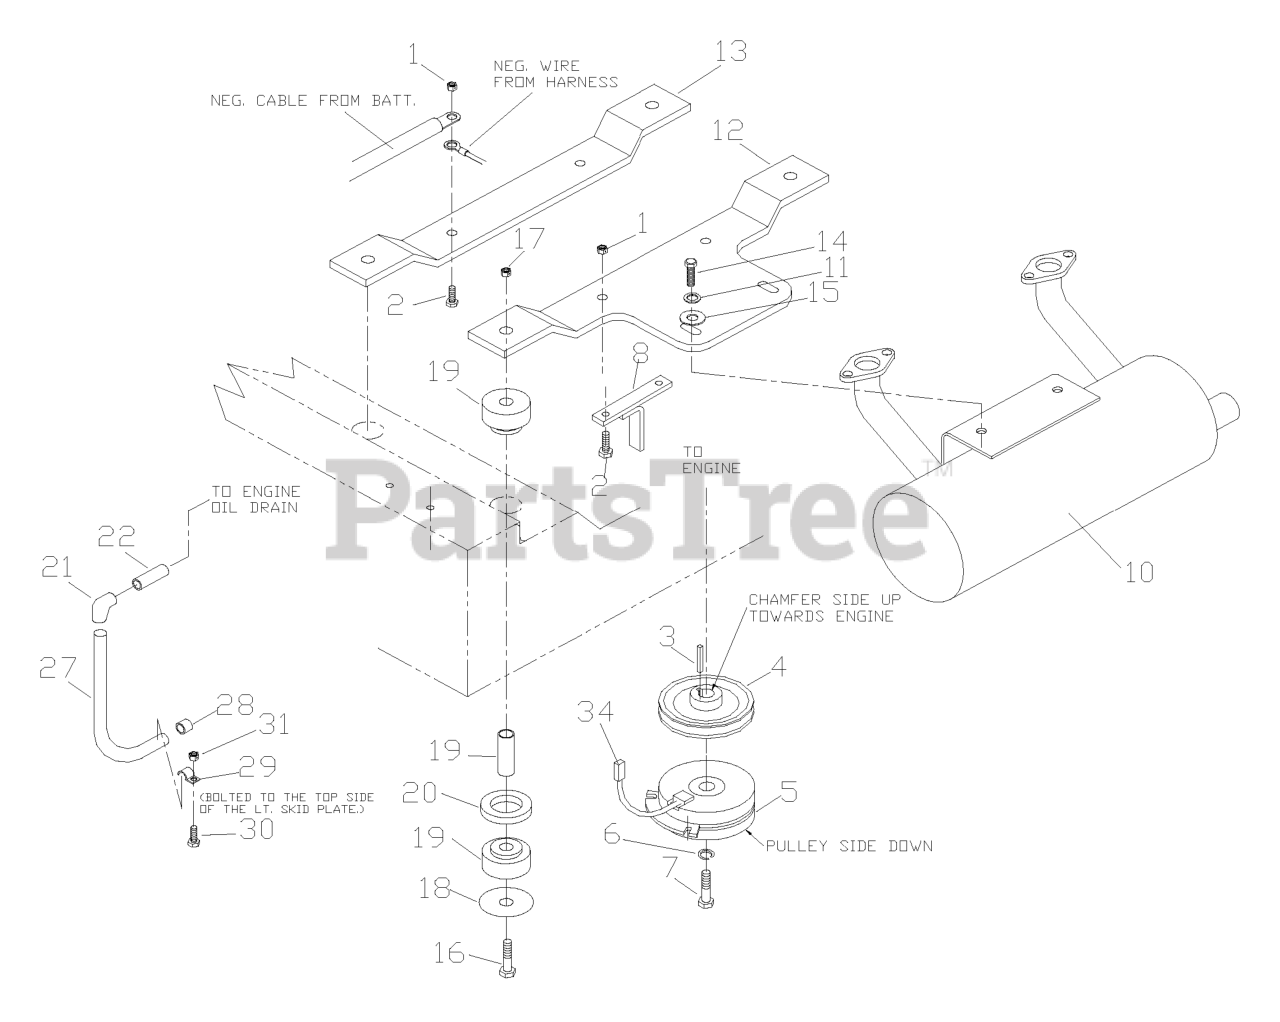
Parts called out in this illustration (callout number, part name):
1	NUT 5/16C CENTERLOCK
2	HCS 5/16C X 1 3/4
3	KEY 1/4" SQ X 1 7/8"
5	ELECTRIC CLUTCH W/CABLE
6	WASHER 7/16 LOCK
7	BOLT 7/16F X 2 1/2
8	CLUTCH TIE DOWN
10	MUFFLER KOHLER GEN II
11	WASHER.LOCK.HVY.HLCL.SPR.5/16
12	REAR ENGINE MOUNT
13	ENGINE MOUNT
14	HCS 5/16C X 3/4
15	WASHER 5/16 FLAT
16	HCS 1/2C X 3 1/4
17	NUT 1/2-13 HEX NYLOC ZD
18	ISOLATOR WASHER
20	ISOLATOR SPACER
21	90 DEG.ELBOW 3/8NPT
22	PIPE 3/8 NPT 1-1/2
27	OIL DRAIN HOSE
30	HCS 1/4C X 3/4 HCS
31	NUT 1/4C CENTER LOCK
32	CHOKE CONTROL, COMPLETE
34	CLUTCH HARNESS
